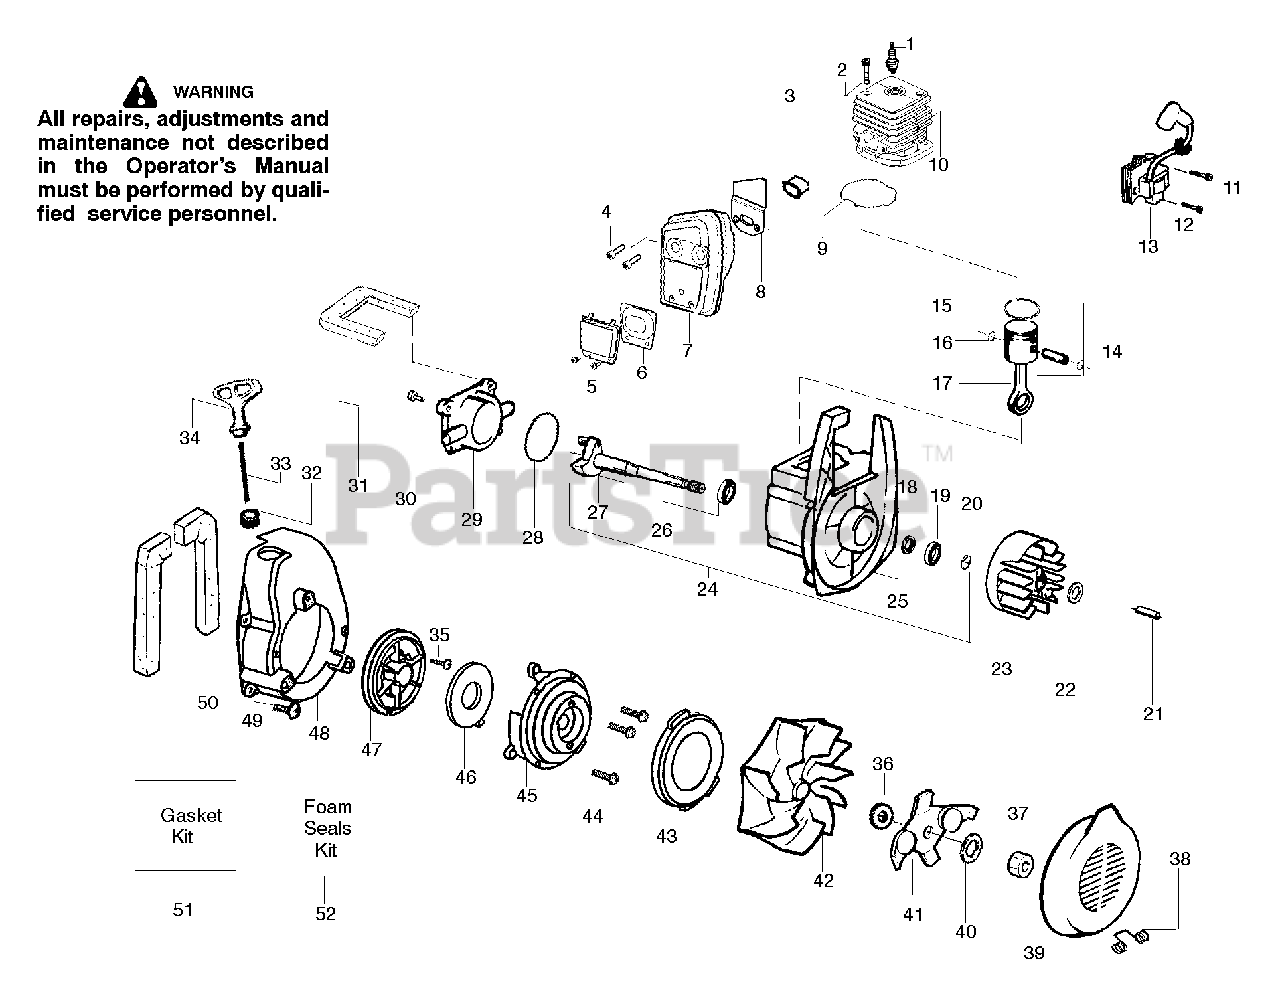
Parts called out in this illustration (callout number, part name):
1	Spark Plug (RCJ-6Y)
3	Insulator-Heat
4	Screw-Muffler-Internal
6	Kit-Spark Screen
7	Kit-Muffler
8	Gasket-Baffle (kit)
9	Gasket-Cylinder (kit)
10	Kit-Cylinder
11	Grommet-Ign. Module
12	Screw-Ignition Module
13	Ignition Module
14	Kit-Piston
15	Piston Ring
16	Retainer-Piston Pin
17	Assy-Connecting Rod
18	Kit-Crankcase Seal
19	Bearing-Outer
20	Retainer Ring-C'chaft
21	Spacer-Flywheel
23	Assy-Flywheel
24	Assy-Crankcase/Crank shaft
25	Assy-Crankcase
26	Bearing-Inner
27	Assy-Crankshaft
28	O-ring-C/case (kit)
29	Cover-Crankcase
30	Screw
31	Foam-219mm (kit)
32	Eyelet-Flange
33	Kit-Rope
34	Handle-Starter
35	Screw-Rope
36	Washer-Belleville
38	Spring-Return Cover
39	Inlet Door
40	Washer-Flat (bv1850 only)
41	Assy-Mulch Blade (bv2000 only)
42	Assy-Impeller
43	Seal-Ring
45	Housing-Pulley
46	Spring-Starter
47	Kit-Starter Pulley
48	Fan Housing
49	Screw
50	Foam-182mm (kit)
51	Kit-Gasket
52	Kit-Foam Seals
